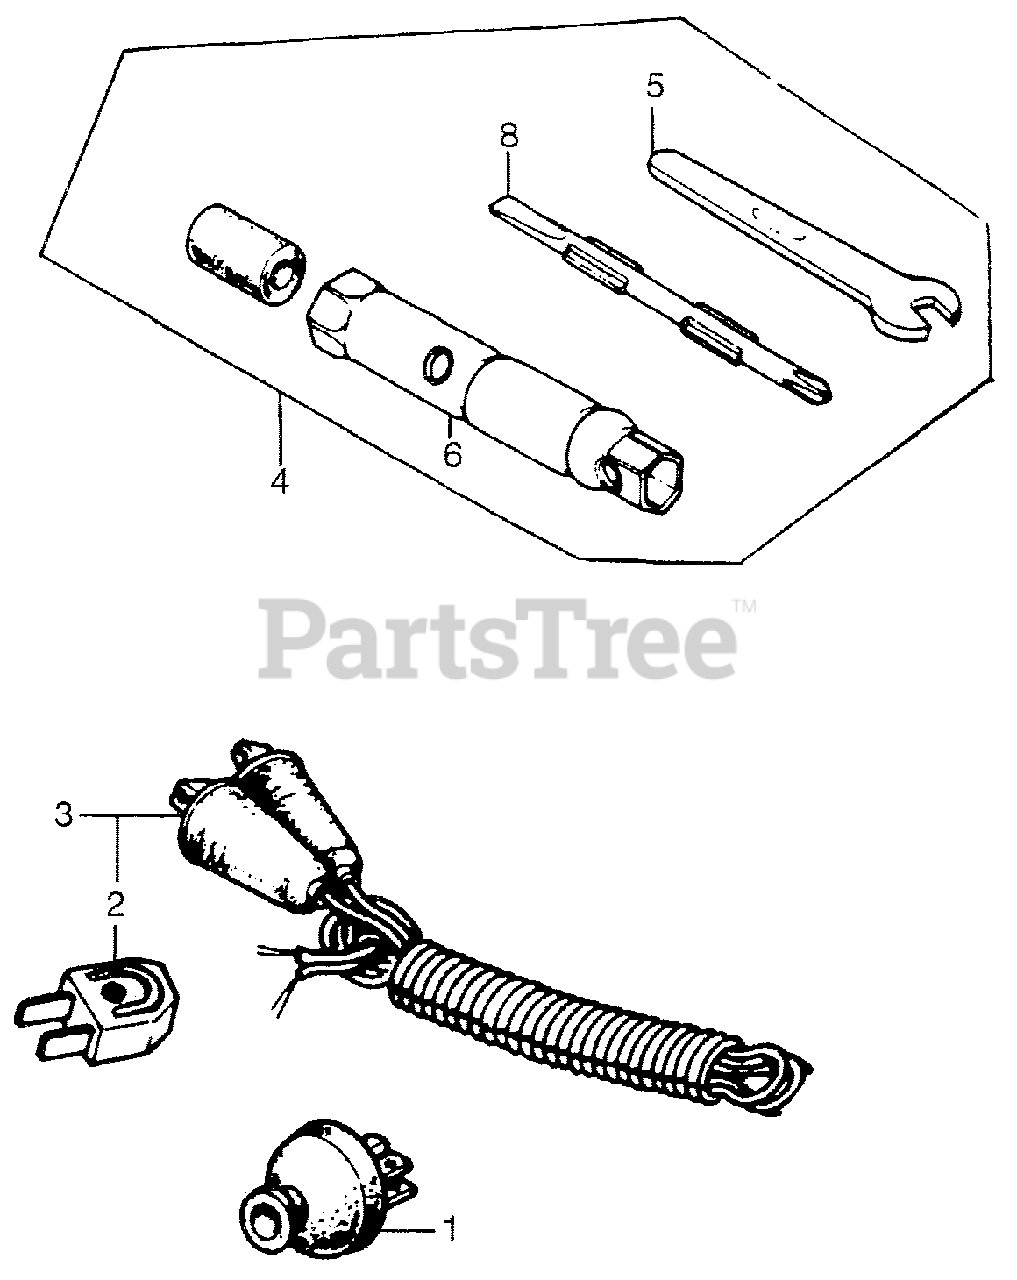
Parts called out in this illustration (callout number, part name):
2	RECEPTACLE ASSY., SWITCH (NOT AVAILABLE)
3	WIRE ASSY., CHARGE
5	WRENCH (8MM) (OPEN END) (NOT AVAILABLE)
6	WRENCH, SPARK PLUG (NOT AVAILABLE)
